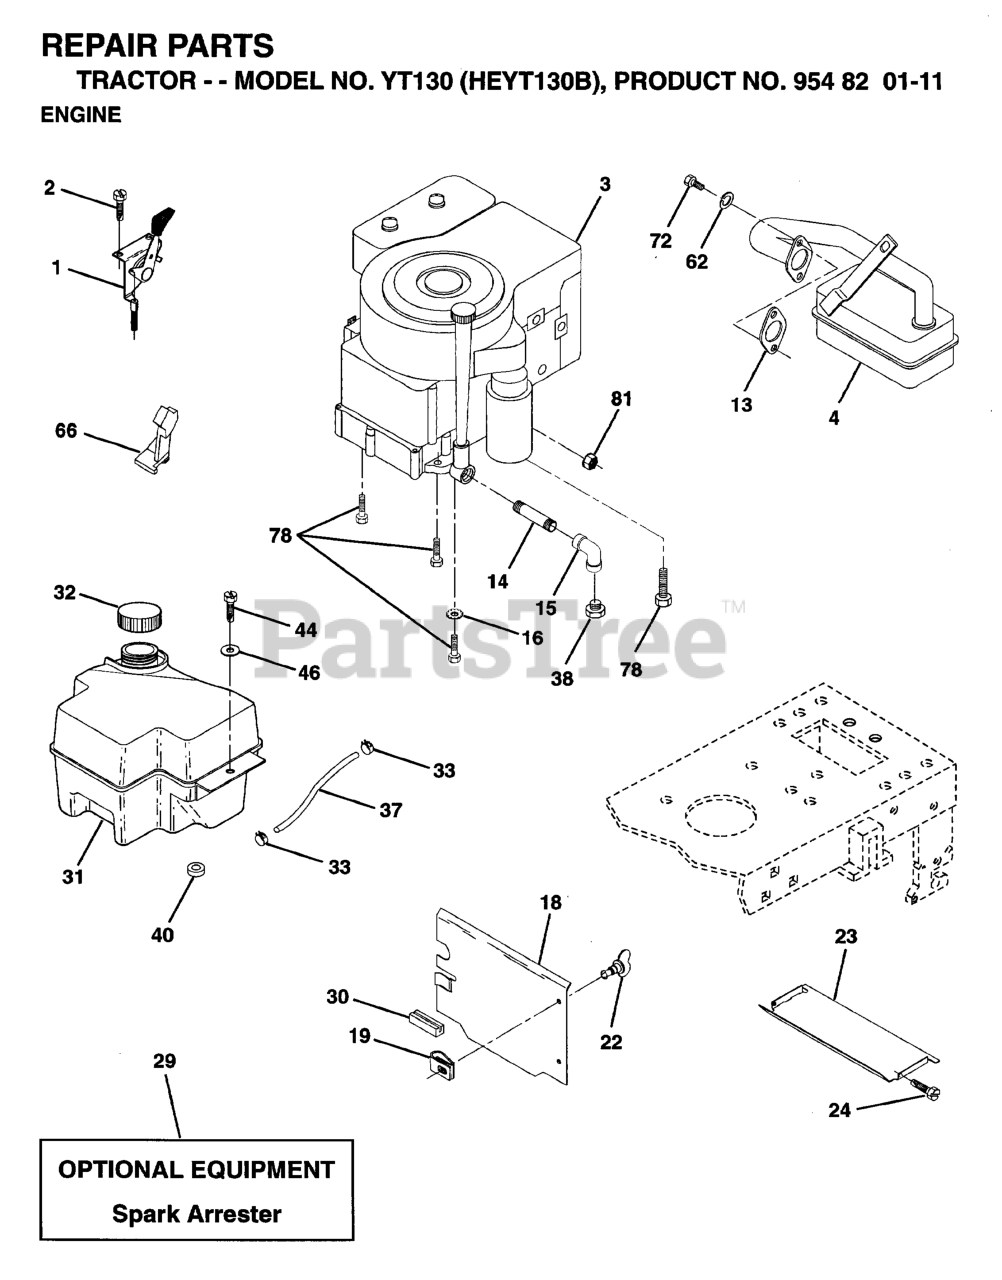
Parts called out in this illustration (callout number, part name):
1	CONTROL
2	SCREW LT
4	MUFFLER.SINGLE.B&S.10-12HP
13	GASKET.ENG.1.313 ID.TIN PLATED
14	Nipple Pipe 3/8 Npt X 3-1/2
15	ELBOW
16	LOCKWASHER
18	HEAT SHIELD
19	RECEPTACLE LT
22	STUD 1/4 TURN
23	HEAT SHIELD
29	KIT.SPARK ARRESTOR 794945 B&S
31	FUEL TANK
32	FUEL CAP
33	HOSE CLAMP
37	LINE.FUEL.20
40	BUSHING.SNAP.NYL.BLK.
44	SCREW HEX CRT
62	WASHER.LOCK.HVY.HLCL.SPR.5/16
66	STOP THROTTLE
72	SCREW
78	SCREW
81	NUT FLANGE 1/4-20 STARTER NUT
